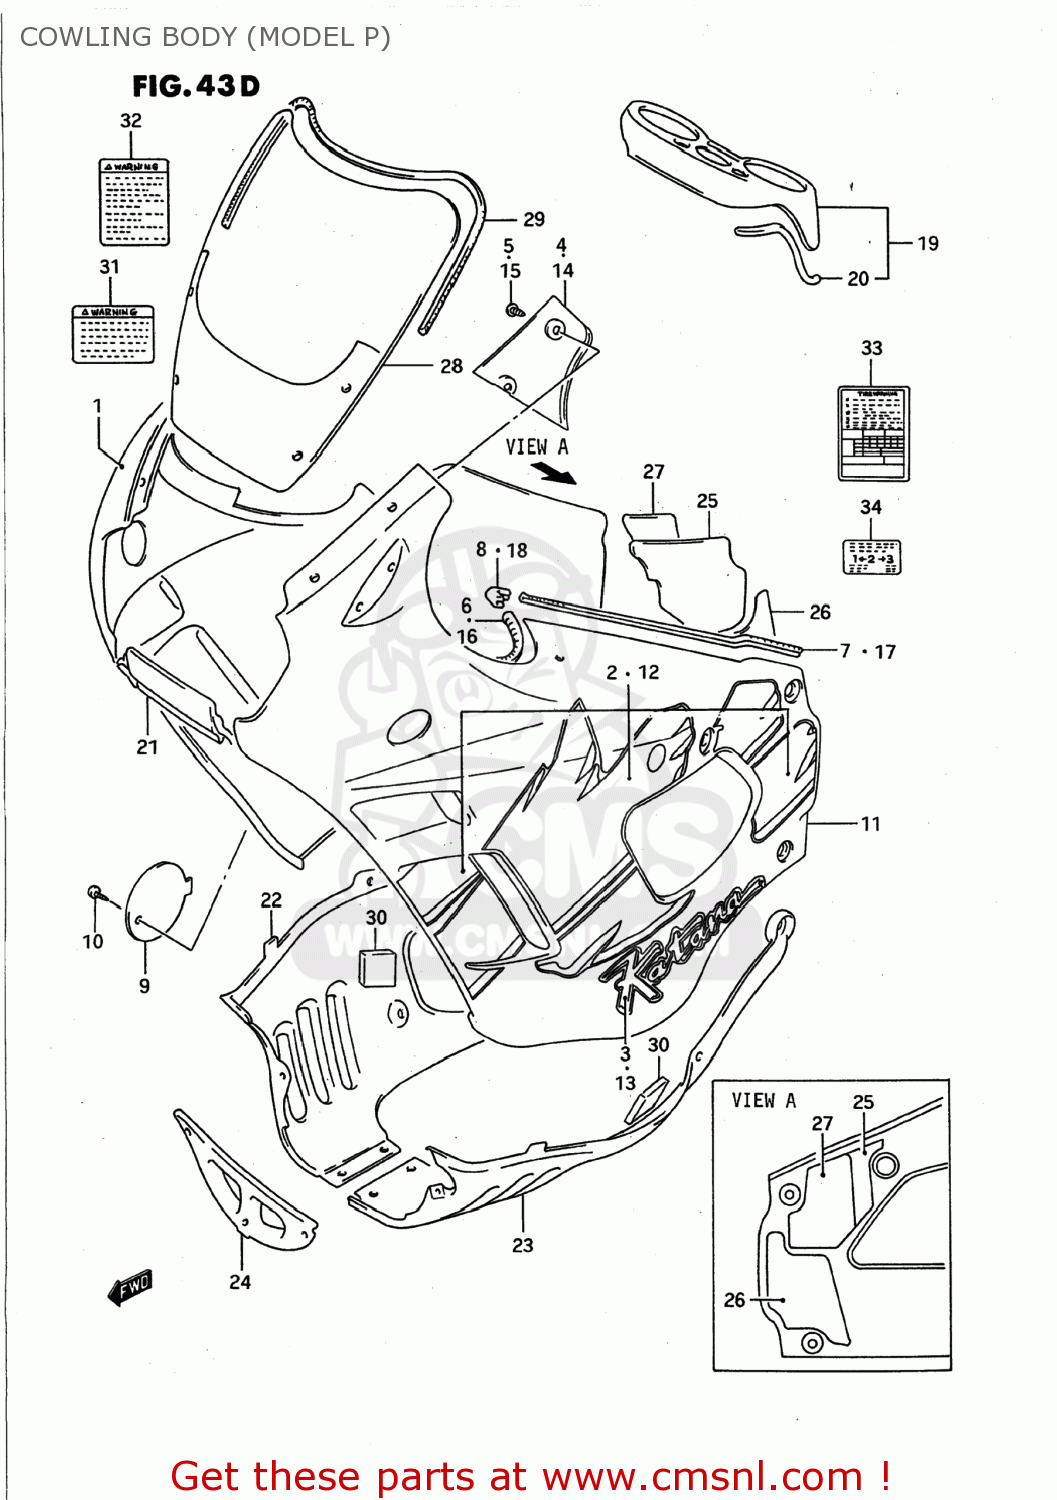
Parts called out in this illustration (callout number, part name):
1	COVER ASSEMBLY,COWLING,RIGHT
2	TAPE SET,BODY COWLING SIDE
3	EMBLEM,BODY COWLING SIDE
4	COVER,METER SIDE,R
5	SCREW
6	MOLD,COWLING
7	MOLDING
8	JOINT,MOLDING END
9	LID,OIL
10	SCREW(6X16)
11	COVER ASSEMBLY,COWLING,LEFT
12	TAPE SET,BODY COWLING SIDE
13	EMBLEM,BODY COWLING SIDE
14	COVER,METER SIDE,LEFT
15	SCREW
16	MOLD,COWLING
17	MOLDING
18	JOINT,MOLDING END
19	COVER,METER
20	MOLDING,METER COVER
21	PANEL,COWLING CTR
22	COVER,COWLING UNDER,R
23	COVER,COWLING UNDER,L
24	COVER,COWLING UNDER FR
25	BALANCER SHEET,COWLING,R
26	SHEET,COWLING BALANCER
27	CUSHION,COWLING,R
28	WINDSCREEN
29	MOLDING
30	CUSHION,UNDER COWLING
31	LABEL
32	LABEL (WARNING SCREEN)
33	LABEL (TIRE AIR PRESSURE)
34	LABEL (REAR SHOCK ABSORBER)
